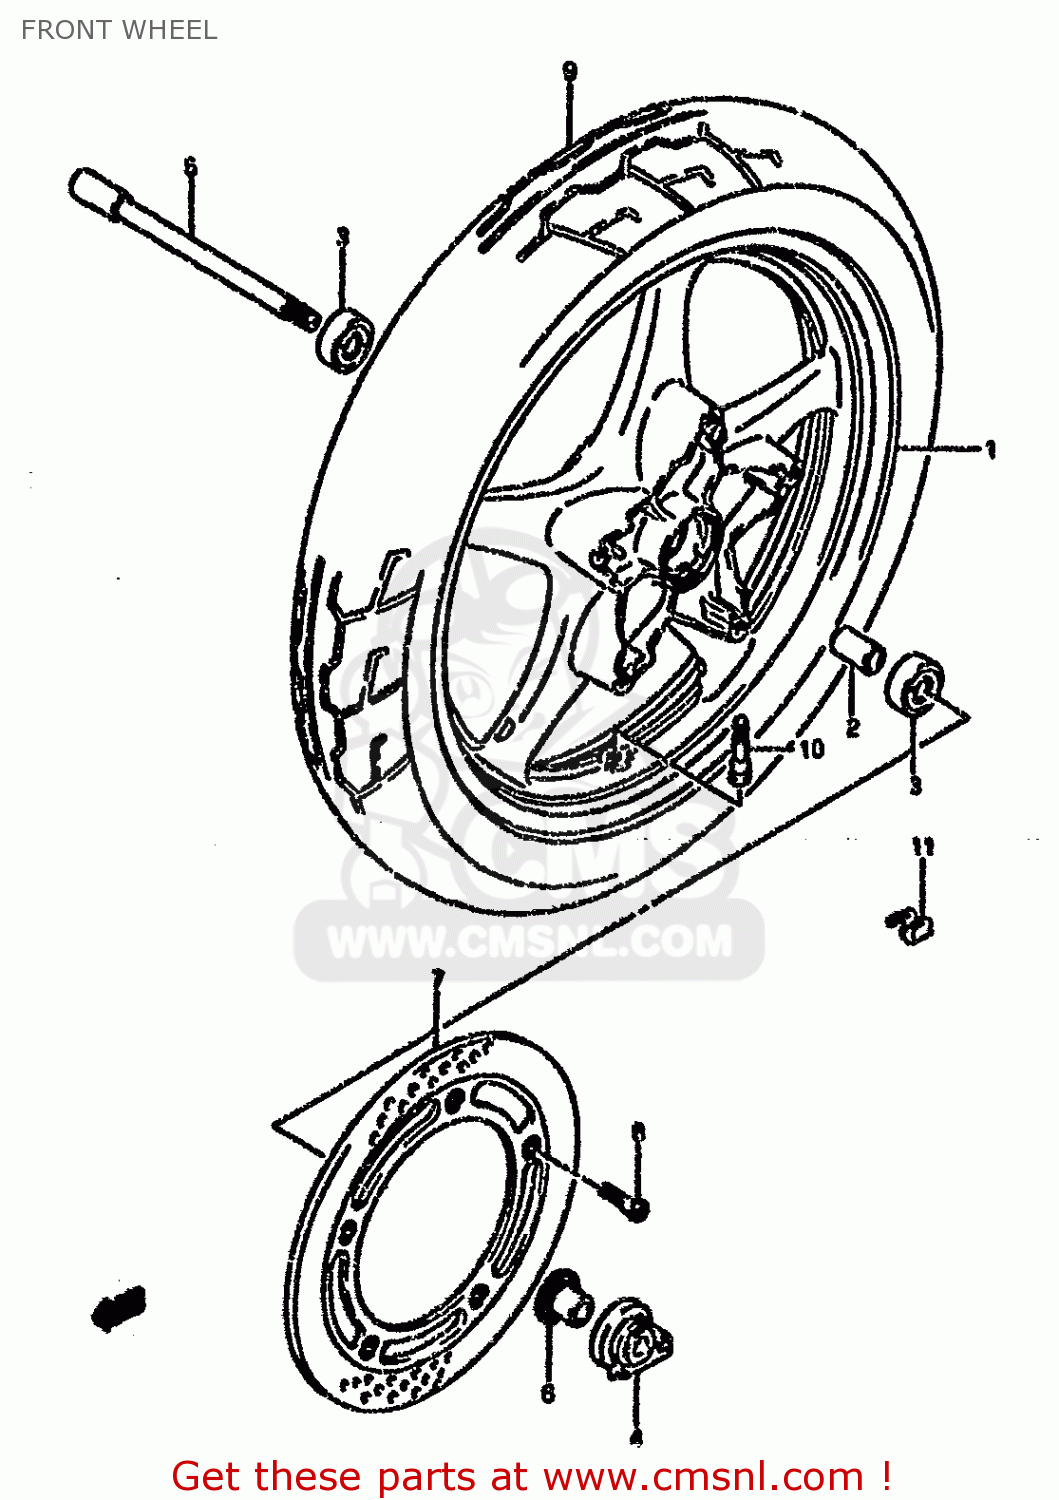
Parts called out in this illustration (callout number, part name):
1	WHEEL,FRONT
2	SPACER(15.3X21.7X63)
3	BEARING
4	BOX ASSEMBLY,SPEEDOMETER GEAR
5	AXLE,FRONT
6	SPACER,FR HUB BEARING,R
7	DISC,FR BRAKE,L
8	BOLT 8X33
9	TIRE 110/80-18 58M,MET
10	VALVE ASSEMBLY,WHEEL,TR412
11	BALANCER,WHEEL
